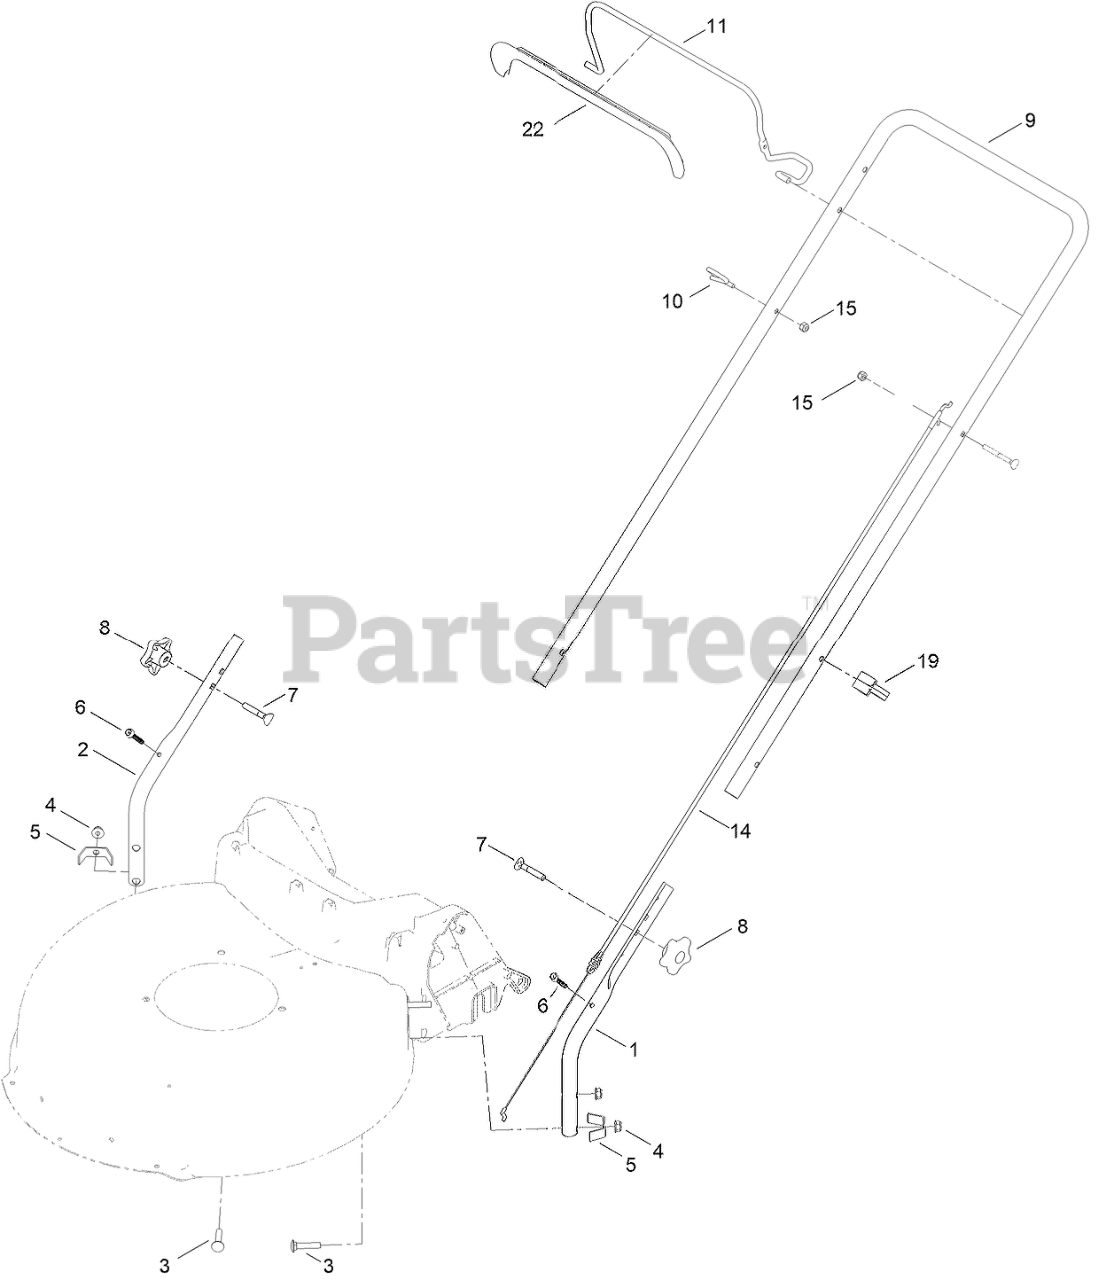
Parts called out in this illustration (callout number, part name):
1	HANDLE-LOWER, LH
2	HANDLE-LOWER, RH
3	BOLT-CARR
4	NUT-FLANGE, NI
5	BRACKET-CHUTE
6	SCREW-FLANGE, SERRATED
7	SCREW-HANDLE
8	KNOB-HANDLE
9	HANDLE-UPPER
10	GUIDE-ROPE
11	BAIL-BRAKE
14	CABLE-BRAKE, ENGINE
15	NUT-LOCK, NI
19	GUIDE-CABLE
22	COVER-BAIL
